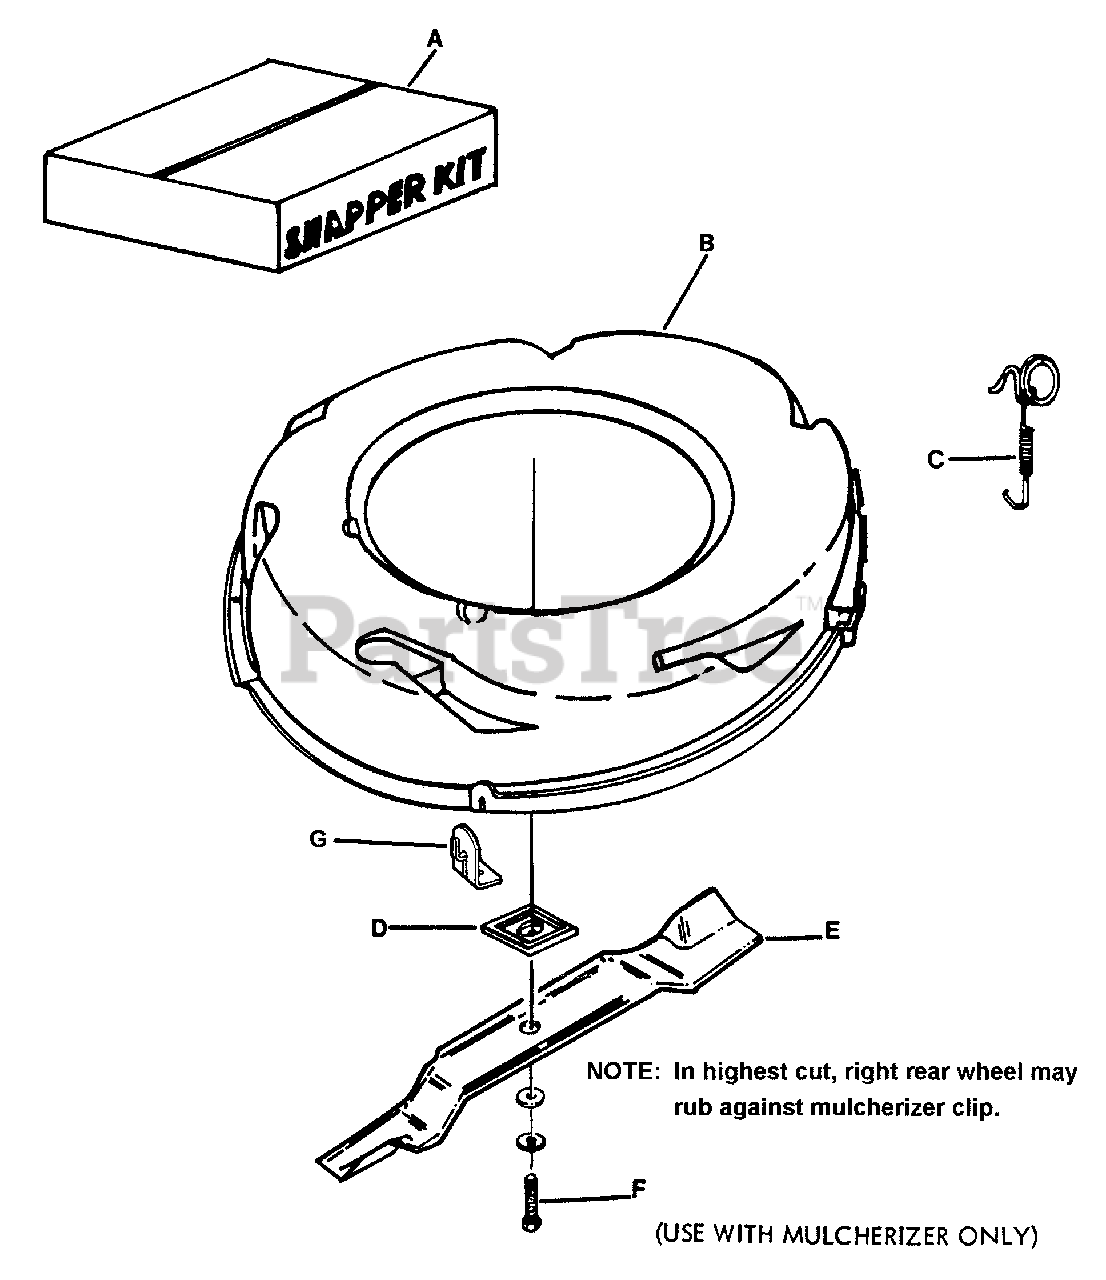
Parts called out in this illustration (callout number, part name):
A	KIT, V21 Mulcherizer
B	LINER, Mulcherizer
C	SPRING, Liner Retaining- (2 - Front)
D	SPACER, Mulcherizer Blade
E	BLADE, V21 Mulcherizer
F	SCREW, 3/8-24 x 2" Hex Head Cap, Grade 5
G	CLIP, Mulcherizer
